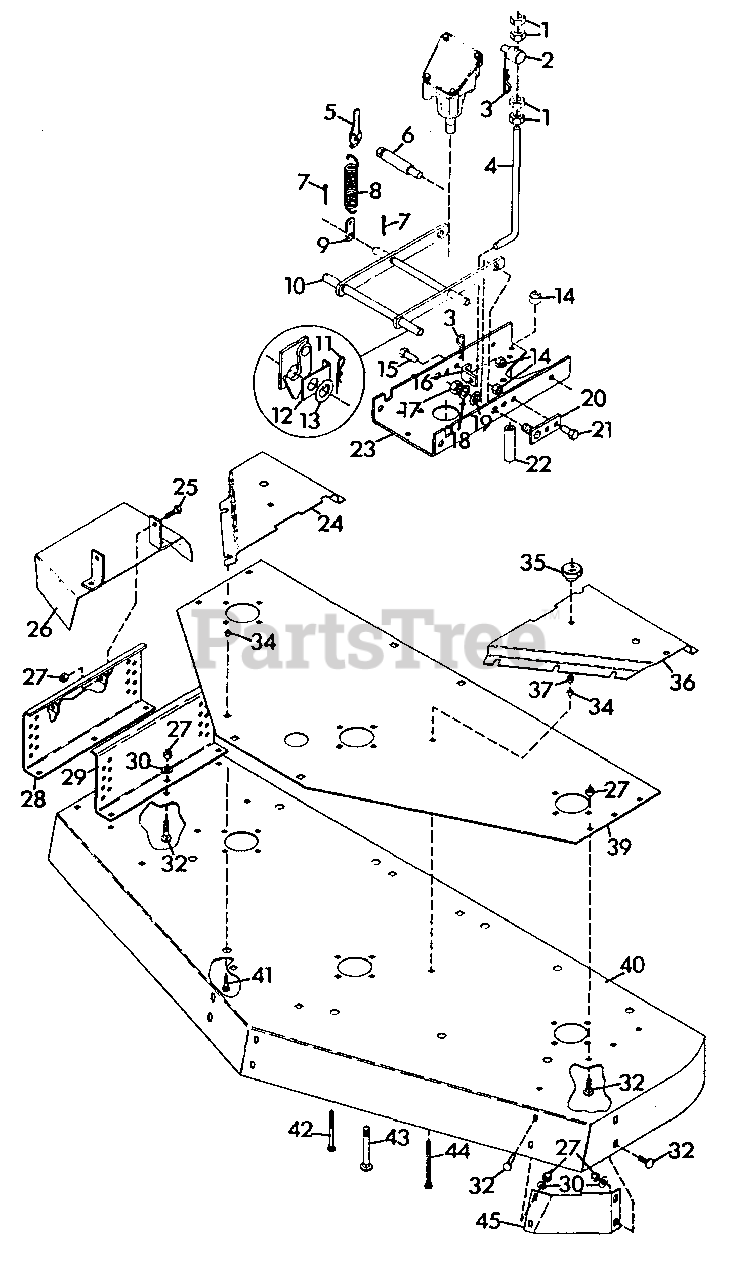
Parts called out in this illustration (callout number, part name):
1	Nut-Jam .50-13 Grade 2
2	Pivot-Mower Lift
3	Pin-Cotter .12 x 2.0
4	Rod-Lift
5	Assembly-Spring Latch Right Hand
5	Assembly-Spring Latch Left Hand
6	Latch-Pin
7	Pin-Cotter .12 x 1.25
8	Spring-Lift .244 x 1.75 x 7.6
9	Strap
10	Weldment-Pivot Arm
11	Pin-Hair-Internal .15 x 2.937
12	Keeper-Mower Pivot
13	Washer-Flat-Steel .813 x 1.370 x .100
14	Nut-Locking-Nylon .50-13 Grade 5
15	Bolt-Hex .50-13 x 1.75
16	Bracket-Lift
17	Nut-Locking .750-10
18	Washer-Hardened-Thrust .758 x 1.23 x .031
19	Bushing-Flange .762 x 1.0 x .580 x 1.48
20	Weldment-Pivot Anchor
21	Bolt-Hex .50-13 x 1.50 Grade 5
22	Spacer .562 x .855 x 2.18
23	Plate-Support
24	Cover-Belt Right Hand
25	Bolt-Hex .38-16 x 1.25 Grade 5
26	Weldment-Discharge Chute
27	Nut-Locking-Nylon .375-16 Grade 2
28	Weldment-60" Hanger
29	Hanger-Left Hand
30	Washer-Flat-Steel .406 x .812 x .065
32	Bolt-Round Head Square Neck .38-16 x 1.0
34	Nut-Locking-Center .50-20
35	Knob
36	Cover-Belt Left Hand
37	Nut-Locking-Nylon .312-18 Grade 2
39	Plate-Support
40	Weldment-60" Mower
41	Bolt-Round Head Square Neck .31-18 x 1.0
42	Bolt-Round Head Square Neck .31-18 x 3.5
43	Bolt-Round Head Square Neck .50-16 x 3.50
44	Bolt-Round Head Square Neck .31-18 x 4.0
45	Baffle-Front
